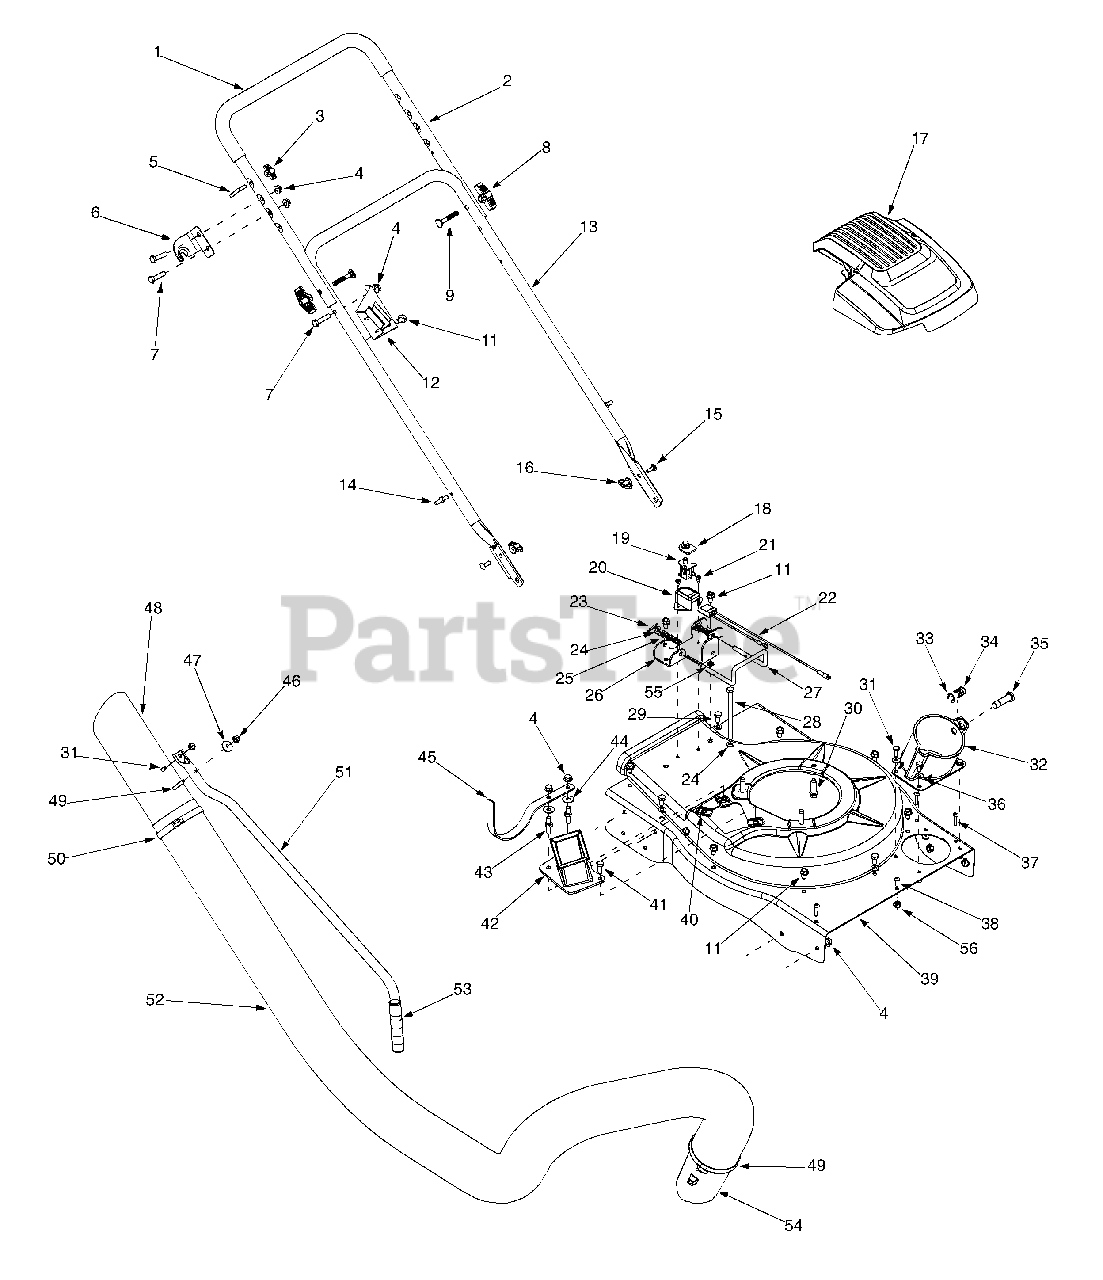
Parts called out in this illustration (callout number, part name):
1	Foam Grip
4	Flange Lock Nut 5/16-18
5	Eye Bolt
7	Hex Cap Screw 5/16-18 x 1.25
8	Handle Knob 5/16-18
9	Carriage Bolt
11	Hex Washer Screw 5/16-18 x.625
12	Lower Handle Bracket
14	Studs
15	Carriage Screw 1/4-20 x.75
16	Wing Nut 1/4-20
17	Shroud
18	Switch Cover
19	Safety Switch
20	Safety Switch Cover
21	Hex Washer Screw #10-16 x.50
22	Wire Harness
23	Cotter Pin
24	Flat Washer.330 ID x.630 OD
25	Compression Spring
27	Lock Rod
28	Hex Cap Screw 5/16-18 x 4.5
29	Hex Cap Screw 5/16-18 x.625
30	Hex Washer Screw 3/8-16 x 1.25
31	Hex Cap Screw 1/4-20 x .620
32	Hose Base Adapter
33	E Ring .500 Dia
34	Compression Spring
35	Clevis Pin
36	Flat Washer ..271 ID x .630 OD
37	Screw #12-16 x 1.0
38	Machine Screw #10 - 24 x .625
40	U-Clip Lock Nut 5/16-18
41	Hex Cap Screw 5/16-18 x.75
43	Stud 5/16-18 x .56
44	Flat Washer .343 ID x .880 OD
47	Spacer
48	Hose Nozzle
49	Hex Cap Screw 1/4-20 x 2.625
50	Adjustment Clamp
52	Vacuum Hose
53	Handle Grip
54	Hose Adapter
55	External L-Washer 5/16
56	Hex Lock Nut #10 - 24
